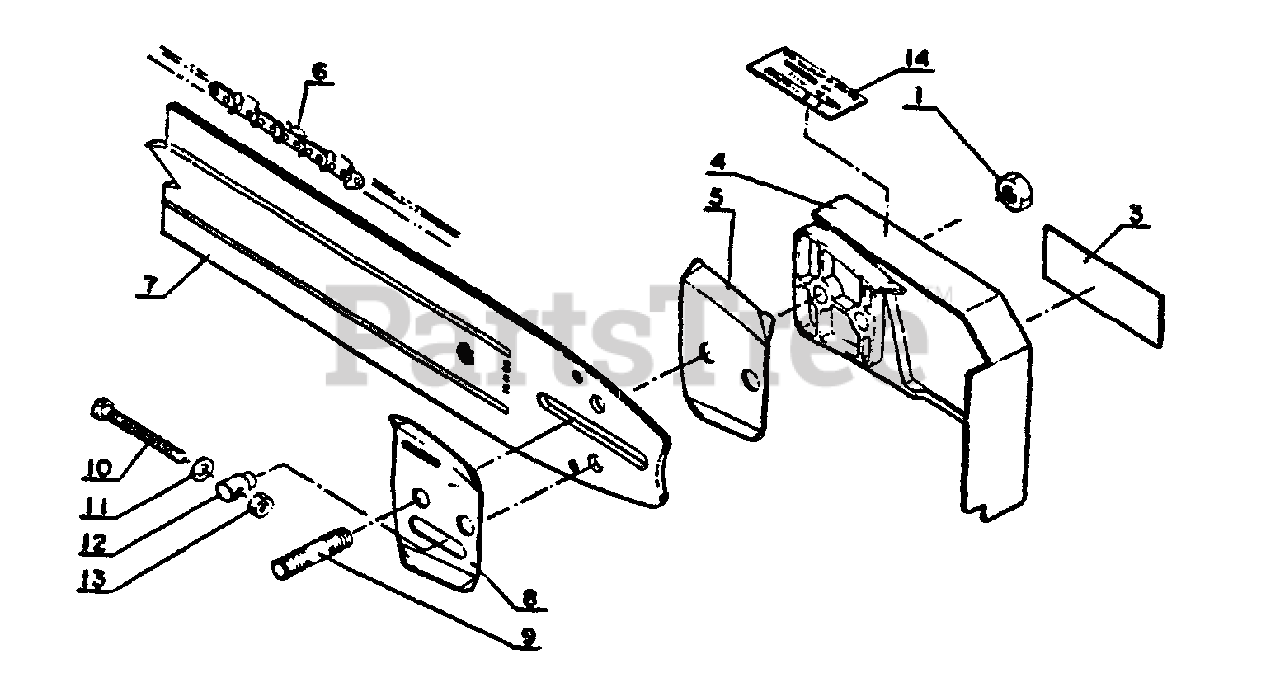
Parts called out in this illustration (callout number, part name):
1	NUT - FLANGE
3	LABEL - ECHO
4	GUARD, SPROCKET
5	PLATE, GUIDE - OUTER
6	CHAIN, SAW
7	GUIDE BAR
8	PLATE, GUIDE - INNER
9	STUD, GUIDE BAR
10	SCREW, TENSIONER
11	WASHER - 5
12	TENSIONER, CHAIN
13	LOCKNUT - 5
